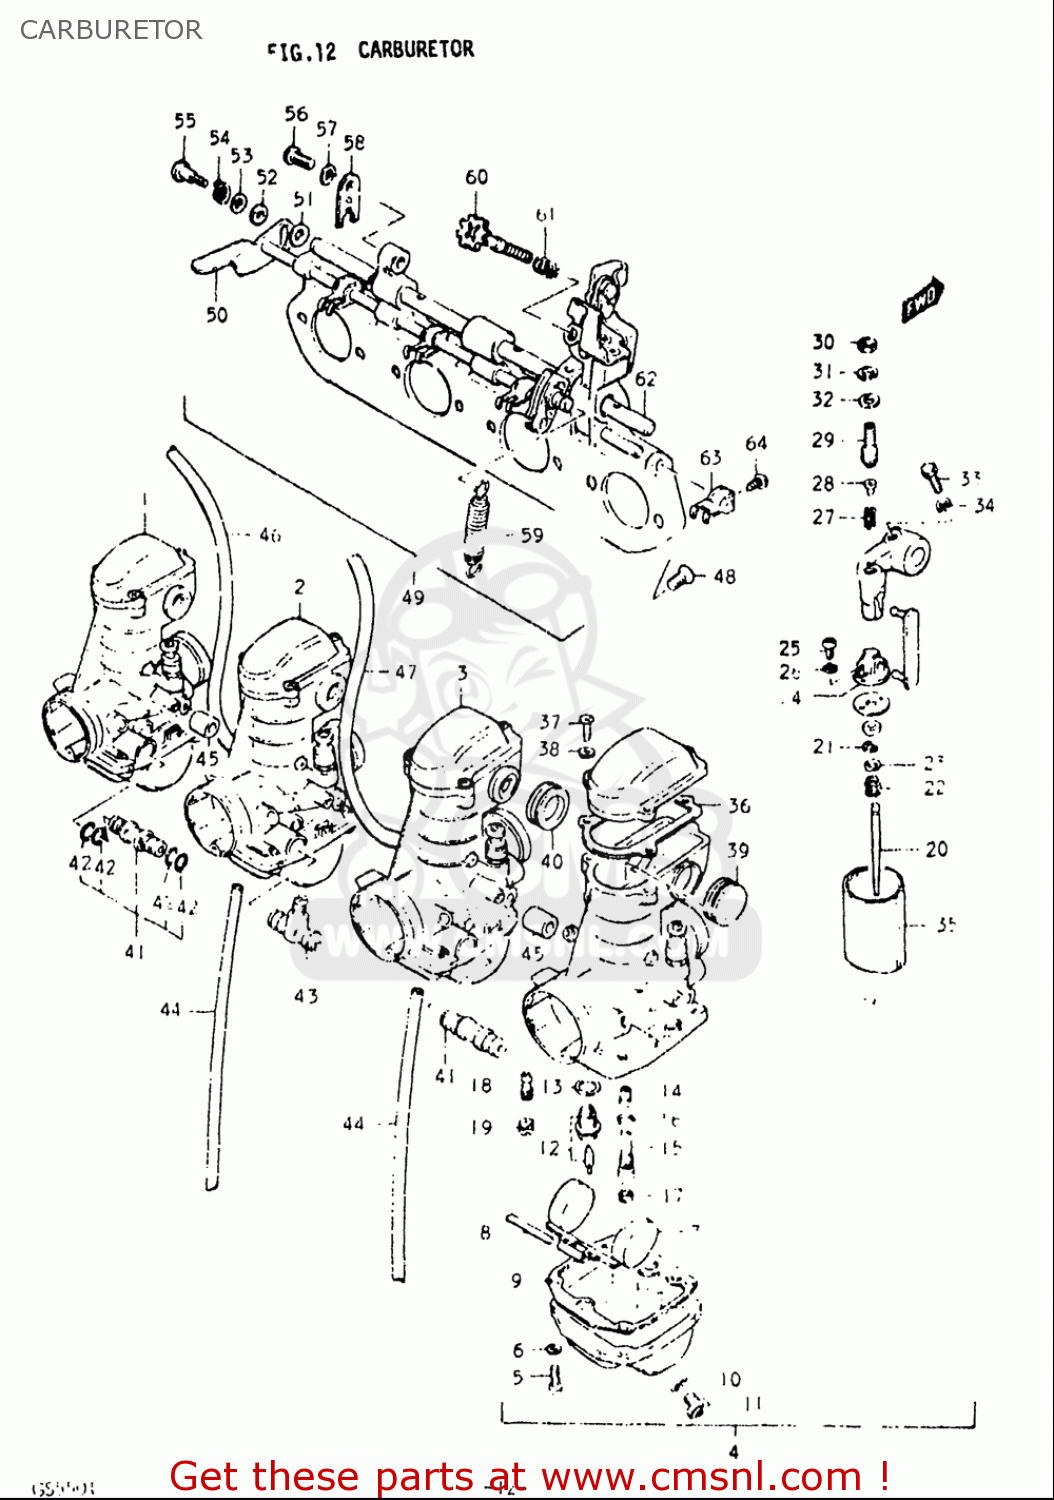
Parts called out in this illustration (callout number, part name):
5	SCREW 4X16
6	WASHER,LOCK
7	FLOAT
8	PIN,FLOAT
9	GASKET,FLOAT CHAMBER (NAS)
10	O RING
11	SCREW
12	VALVE ASSY,NEEDLE
13	GASKET,VALVE SEAT (NAS)
15	PIPE,BLEEDER
16	O RING
17	JET,MAIN
18	JET,PILOT(15)
19	JET,AIR(50)
21	CLIP
22	SPRING
23	WASHER,JET NEEDLE
25	SCREW
26	WASHER,LOCK
30	NUT
31	WASHER,LOCK
32	WASHER
33	BOLT
34	WASHER,LOCK
36	GASKET (NAS)
37	SCREW 4X16
38	WASHER,LOCK
40	SEAL
42	O-RING
45	HOSE(5.8X12.2X600)
46	HOSE(4.5X8.5X600)
47	HOSE(4.5X8.5X600)
48	SCREW
51	WASHER,STARTER SHAFT
52	WASHER
53	WASHER,STARTER SHAFT
54	SPRING
56	SCREW
57	WASHER,LOCK
64	SCREW
